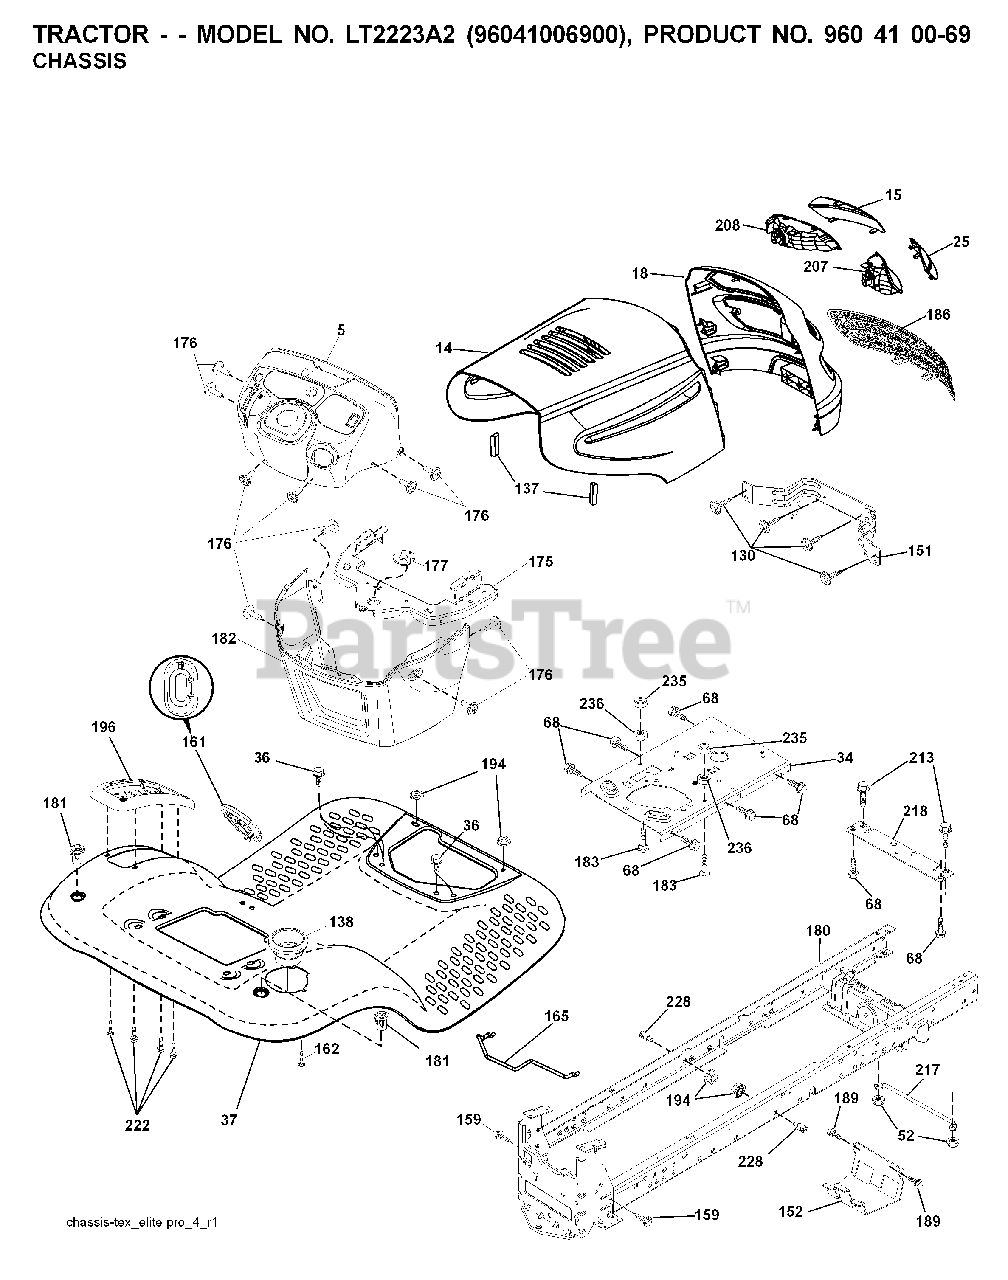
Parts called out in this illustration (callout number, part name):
34	PLATE.ENGINE.WELDED.CHASSIS
36	SCREW 5/16"
52	LOCKNUT
130	SCREW.#10 X 0.750.BOS THREAD
137	BUMPER.HOOD.LARGE.1.75"
138	CUPHOLDER.TL.TEX.BLACK
151	BRACKET PIVOT
152	SHIELD BROWNING
159	SCREW, 3/8-16X3/4
161	WINDOW.FUEL.LT.TEX.BLACK
162	SCREW.HI-LO.CONSOLE
165	SUPPORT.TANK.REAR.W/TE
175	CROSSMEMBER.LT
176	SCREW.#10-24X5/8.RN.QU
177	BUSHING STEERING
180	CHASSIS
181	FEND/FTRST.PCH.CPH.NFW
182	DASH.LOWER.LT.CCS
183	BOLT.5/16-18X1-1/4 FULL.THREAD
189	SCREW
194	NUT LOCK HEX FLANGE 5/16-18
196	CONSOLE.ASM.DECKLFT.BL/RBT.TLT
207	BEZEL GRILL RH
208	BEZEL GRILL LH
213	BOLT
217	ROD.PIVOT.HOOD
218	X-PIECE.HOOD.STOP.NON/
222	SCREW.1/4-20X5/8
228	STUD.FASTNER.W/ANTI-ROTATE
235	SPACER FENDER
236	NUT.CENTERLOCK.5/16-
